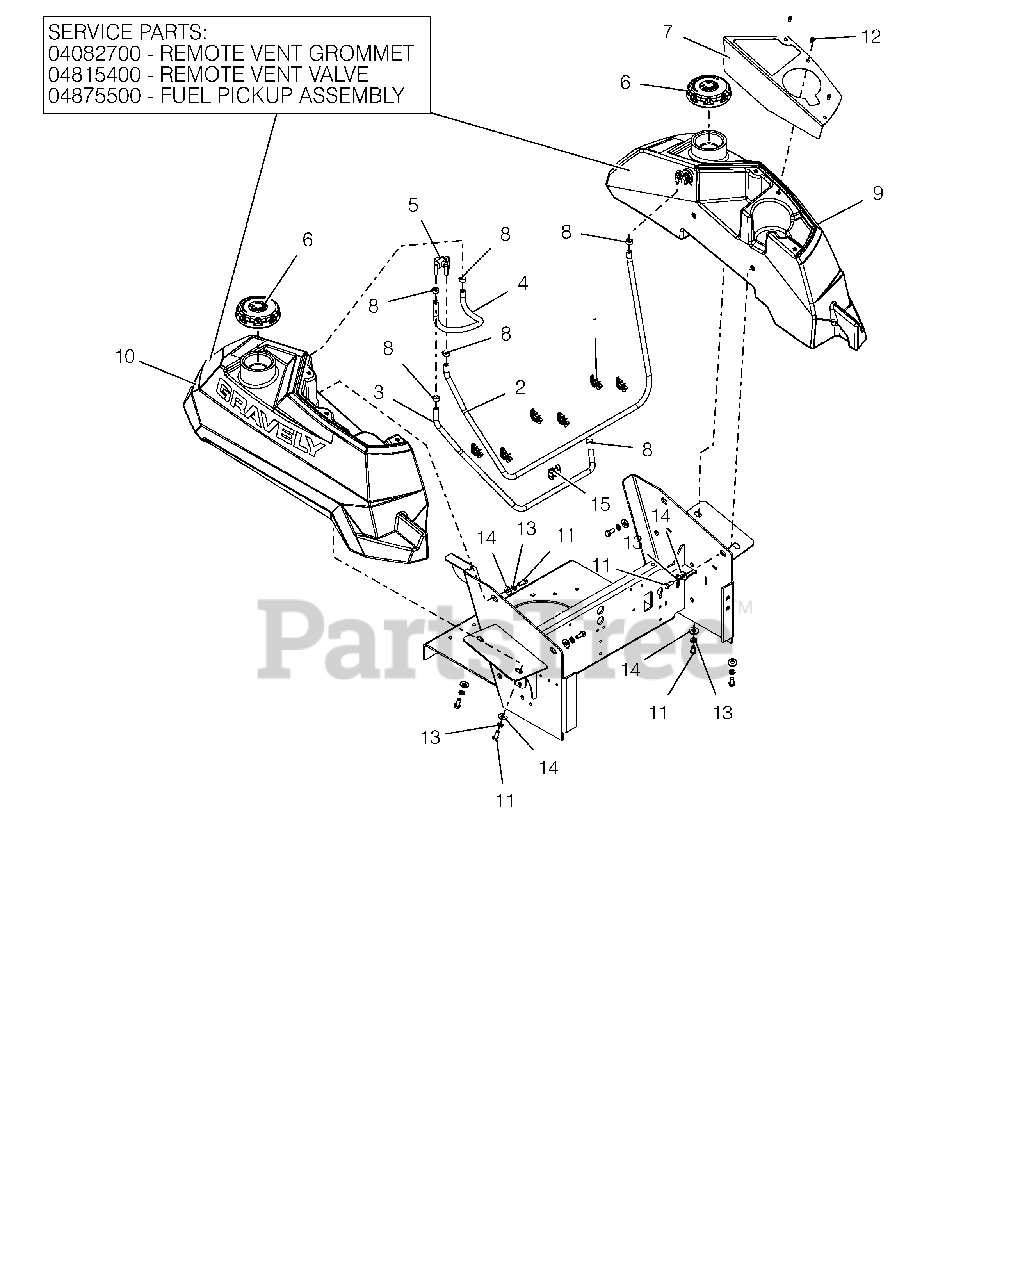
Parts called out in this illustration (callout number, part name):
1	WIRE CLIP
2	HOSE, .25 LOW-PERM BULK GAS
3	HOSE, .25 LOW-PERM BULK GAS
4	HOSE, .25 LOW-PERM BULK GAS
5	VALVE, FUEL
6	CAP, FUEL NONVENT AUTOLOCK
7	PT CUPHOLDER PANEL - RED
8	CLAMP, FUEL LINE
9	ASM,LH PRO-TURN CARB FUEL TANK
10	ASM,RH PRO-TURN CARB FUEL TANK
11	@BLT-HEX .31-18X.75 GR5 YWZC
12	SCR-MCH 10-24X.38 HWHSTAINLESS
13	@WSHR-LK .31X.078 REG YWZC
14	@WSHR-FL-STL.38X.875X.083 YWZC
15	CLIP, T, .38-.50
16	GROMMET, REMOTE VENT NITRILE
17	VALVE, 2-WAY
18	ASSM,LRG TANK FUEL PICKUP LINE
